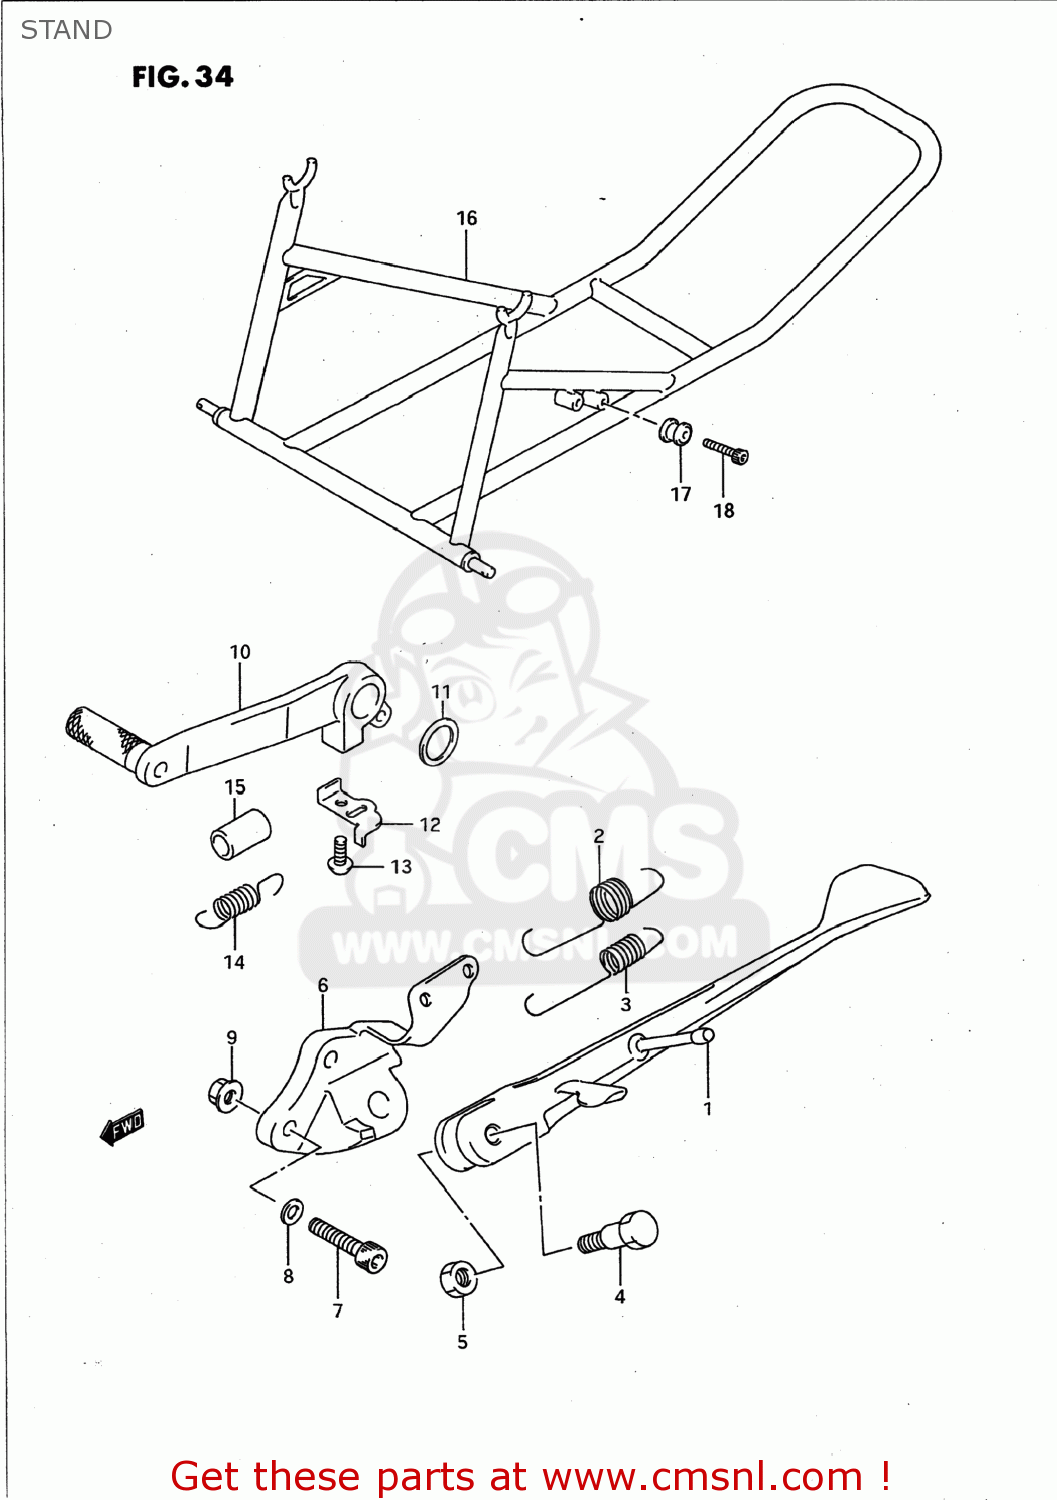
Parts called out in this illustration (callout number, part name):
1	STAND,PROP
2	SPRING
3	SPRING
4	BOLT(10X38)
5	NUT
6	BRACKET,PROP STAND
7	BOLT
8	WASHER
9	NUT
10	PEDAL,BRAKE
11	WASHER(18X24X1)
12	HOOK,RETURN SPRING
13	BOLT
14	SPRING
15	TUBE,BRAKE SPRING GUIDE
16	STAND ASSEMBLY,REAR
17	HOLDER,STAND
18	BOLT
